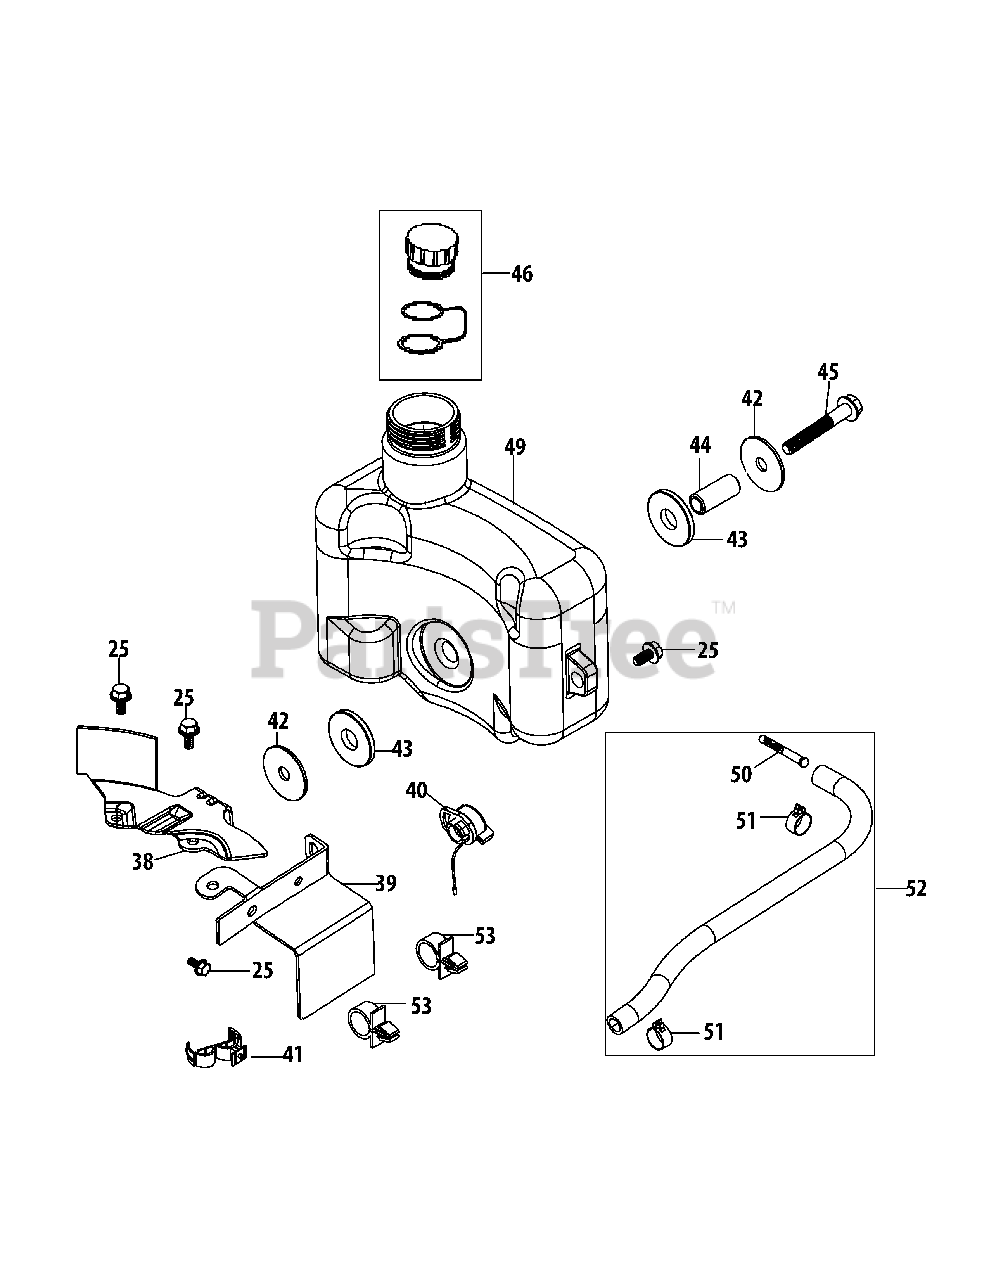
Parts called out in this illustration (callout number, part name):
25	Bolt M6X14
38	Fuel Tank Bottom Bracket
39	Fuel Tank / Console Bracket
40	Ignition Switch
41	Wire Clamp
42	Fuel Tank Washer
43	Rubber Bushing
44	Fuel Tank Bushing
45	Bolt M8X50
46	Fuel Cap Assembly
49	Fuel Tank Assembly
50	Fuel Filter
51	Fuel Hose Clamp
52	Fuel Line Kit
53	Plastic Support Clamp
